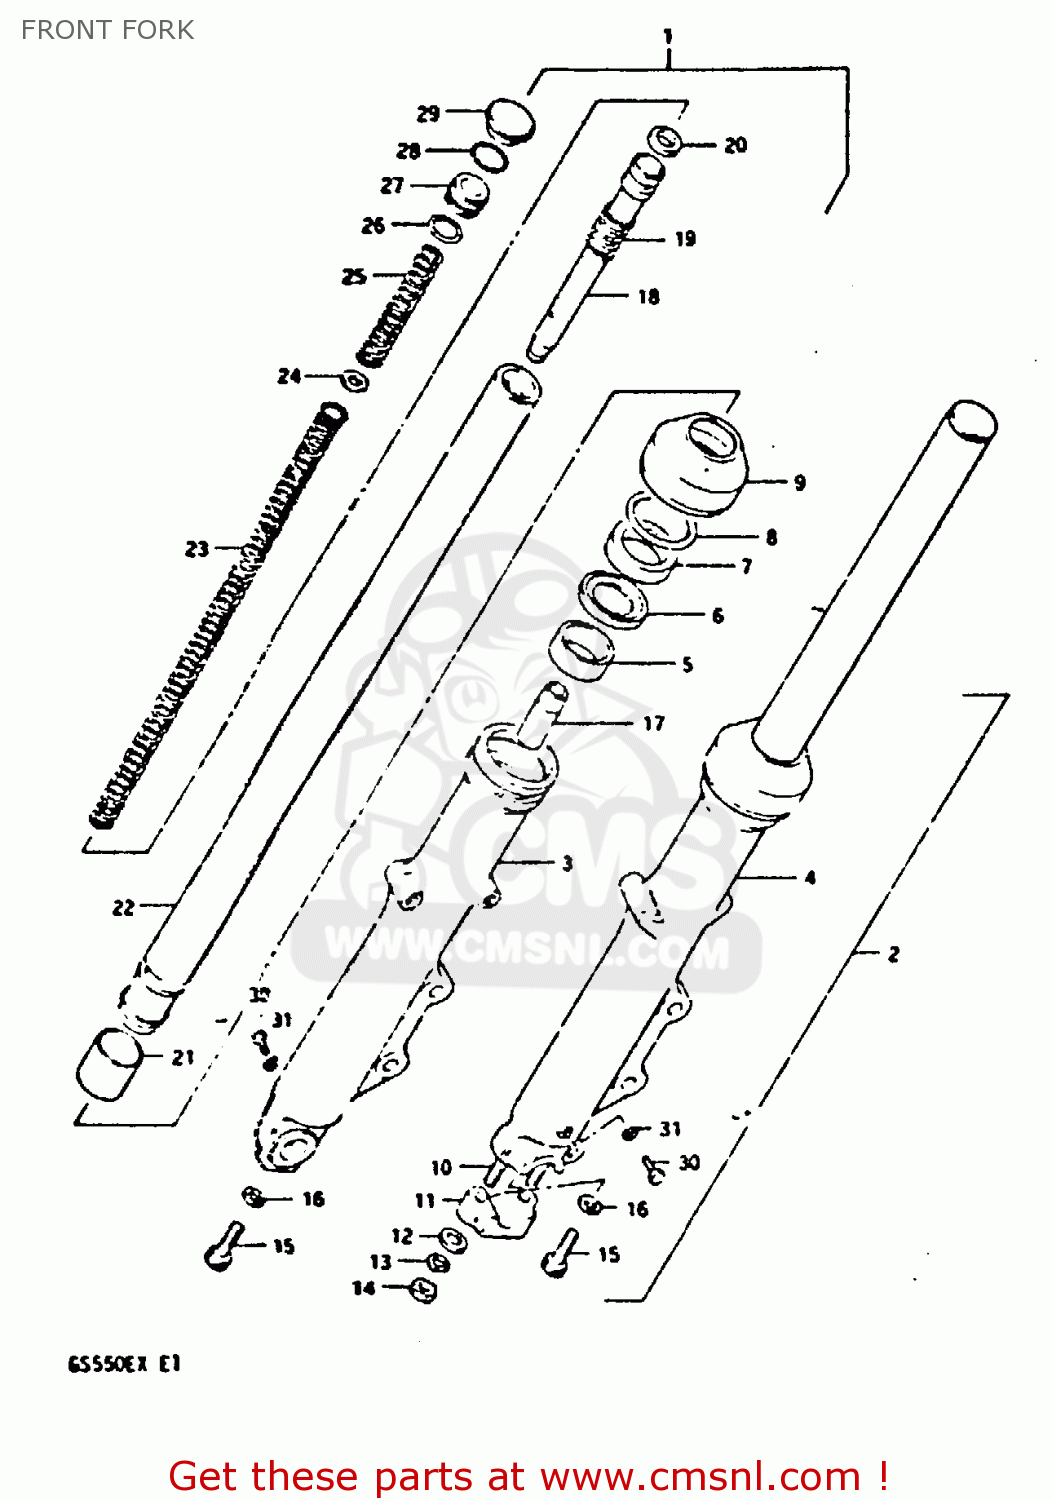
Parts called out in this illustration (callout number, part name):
1	DAMPER ASSY, RH
2	DAMPER ASSY, LH
3	TUBE,FORK,OUTER,RIGHT
4	TUBE,OUTER,LEFT
5	BUSH,GUIDE
6	SPACER,SEAL
7	OIL SEAL,FRONT FORK
8	CIRCLIP,FORK OIL SEAL
9	BOOT
10	STUD BOLT
11	HOLDER, AXLE
12	WASHER
13	LOCK WASHER
14	NUT
15	BOLT(8X27)
16	GASKET (NAS)
17	PIECE,OIL LOCK
18	CYLINDER
19	SPRING,FORK REBOUND
20	RING
21	PISTON
22	TUBE,FORK,INNER
23	SPRING B
24	WASHER,SPRING
25	SPRING A
26	O-RING
27	SPRING SEAT B
28	RING,STOPPER
29	CAP,FRONT FORK
30	BOLT(6X8)
31	GASKET,DRAIN,PLUG (NAS)
